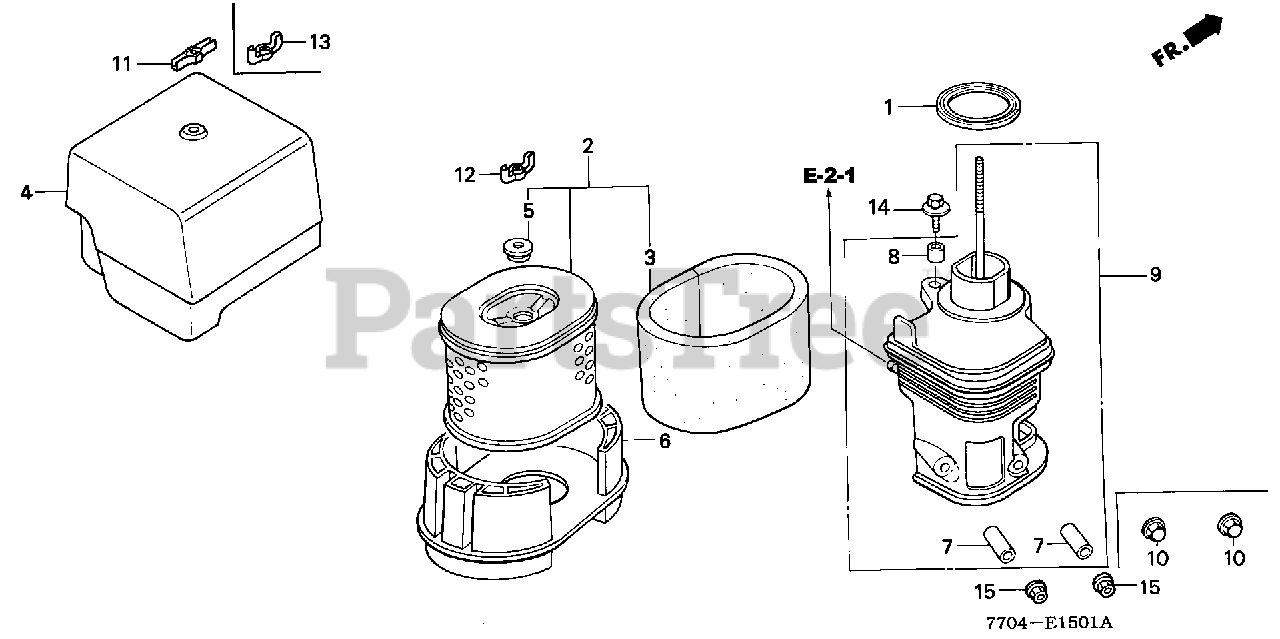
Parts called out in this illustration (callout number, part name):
1	GASKET, ELBOW
2	ELEMENT, AIR CLEANER (DUAL)
3	FILTER (OUTER)
4	COVER, AIR CLEANER
5	GROMMET, AIR CLEANER
6	NOSE, MUFFLER
7	COLLAR, AIR CLEANER
8	COLLAR B, AIR CLEANER
9	ELBOW, AIR CLEANER
12	NUT, TOOL BOX SETTING
13	NUT, TOOL BOX SETTING
14	BOLT-WASHER (6X22)
15	NUT, FLANGE (6MM)
